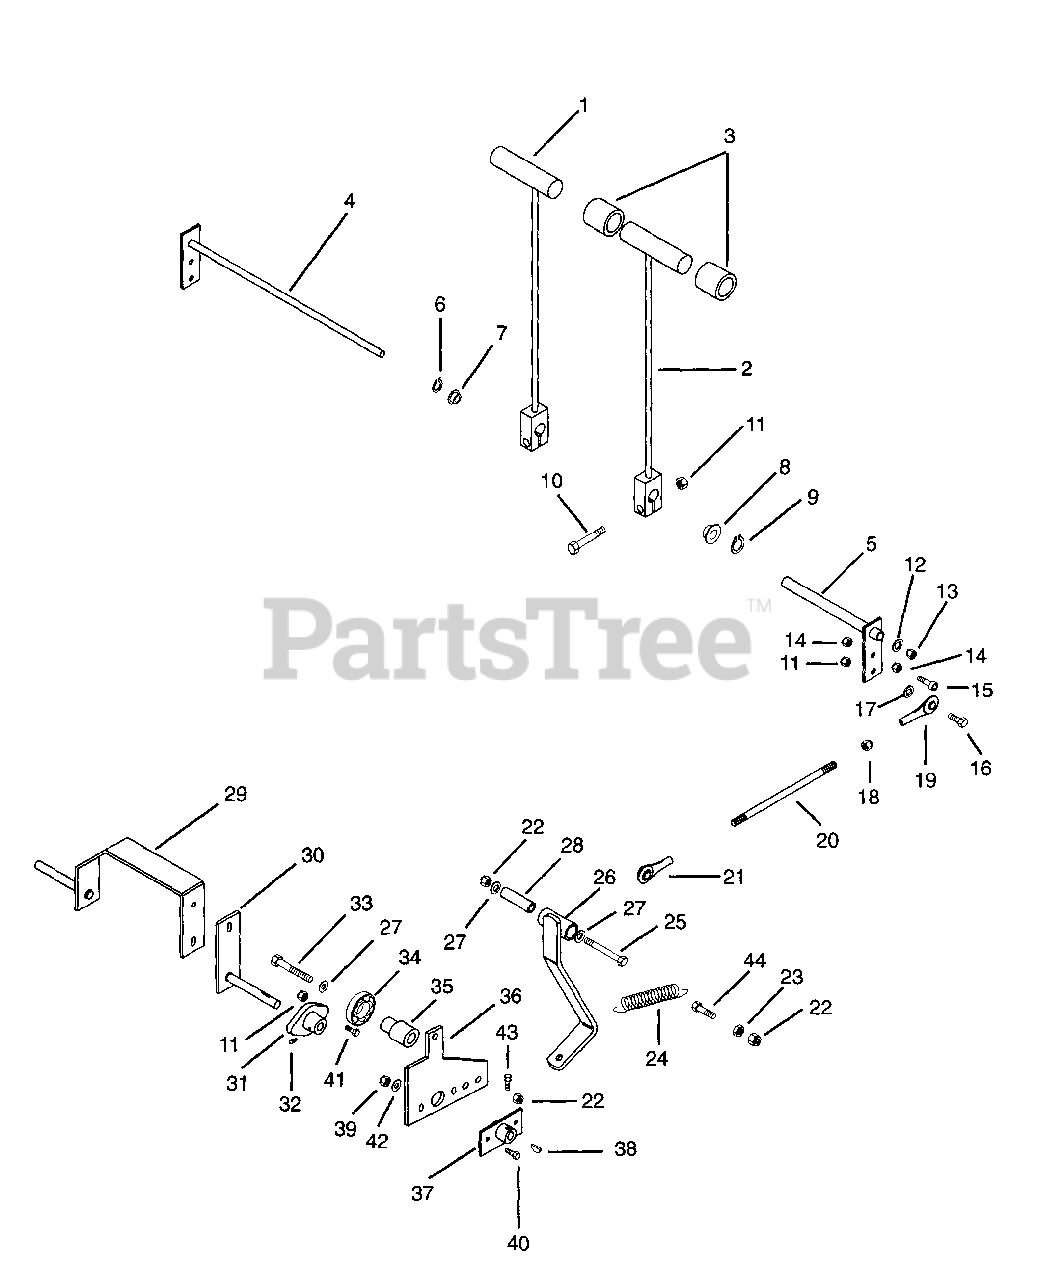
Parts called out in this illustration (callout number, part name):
1	Weldment, Steering Lever Left Hand
2	Weldment, Steering Lever Right Hand
3	Grip, T-Bar
4	Weldment, Steering Left Hand
5	Weldment, Steering Tube Right Hand
6	Ring-Retaining-External .500 x .460
7	Bushing-Flange .515 x .750 x .745 x 1.00
8	Bushing-Flange .762 x 1.0 x .580 x 1.48
9	Ring-Retaining-External .689 x .077
10	Bolt-Hex .31-18 x 1.50 Grade 5
11	Nut-Locking-Nylon .312-18 Grade 2
12	Washer-Flat-Steel .531 x 1.062 x .095
13	Nut-Locking-Nylon .50-13 Grade 5
14	Nut-Hex .312-18 Grade 2
15	Screw-Set .32-18 x 1.50
16	Bolt-Hex .31-18 x 1.25 Grade 2
17	Washer-Flat-Steel .344 x .688 x .065
18	Nut - 5/16-24, Hex, Plated
19	Rod End, 5/16" Female
20	Rod, Steering Adjuster
21	Rod End, 5/16-24 Left Hand Female
22	Nut-Locking-Nylon .375-16 Grade 2
23	Nut-Hex .375-16 Grade 2
24	Spring-Tension .063 x .62 x 2.75
25	Bolt-Hex .38-16 x 2.75 Grade 5
26	Weldment, Neutral Detent
27	Washer-Flat-Steel .406 x .812 x .065
28	Shaft, Jack
29	Weldment, Pump Control Right Hand
30	Weldment, Pump Control Left Hand
31	Bushing, Flanged
32	Fitting-Lube .25-28 x .256
33	Bolt-Hex .38-16 x 2.00 Grade 5
34	Bearing-Ball .500 x 1.375 x .437
35	Hub, Bearing Mount
36	Arm, Speed Control
37	Weldment, Neutral Adjuster
38	Key-Woodruff .13 x .75
39	Nut-Locking-Nylon .250-20 Grade 2
40	Bolt-Hex .25-20 x .75 Grade 5
41	Bolt-Hex .31-18 x 1.00 Grade 5
42	Washer-Flat-Steel .281 x .620 x .065
43	Bolt-Hex .25-20 x .50 Grade 5
44	Bolt-Hex .38-16 x 1.125
